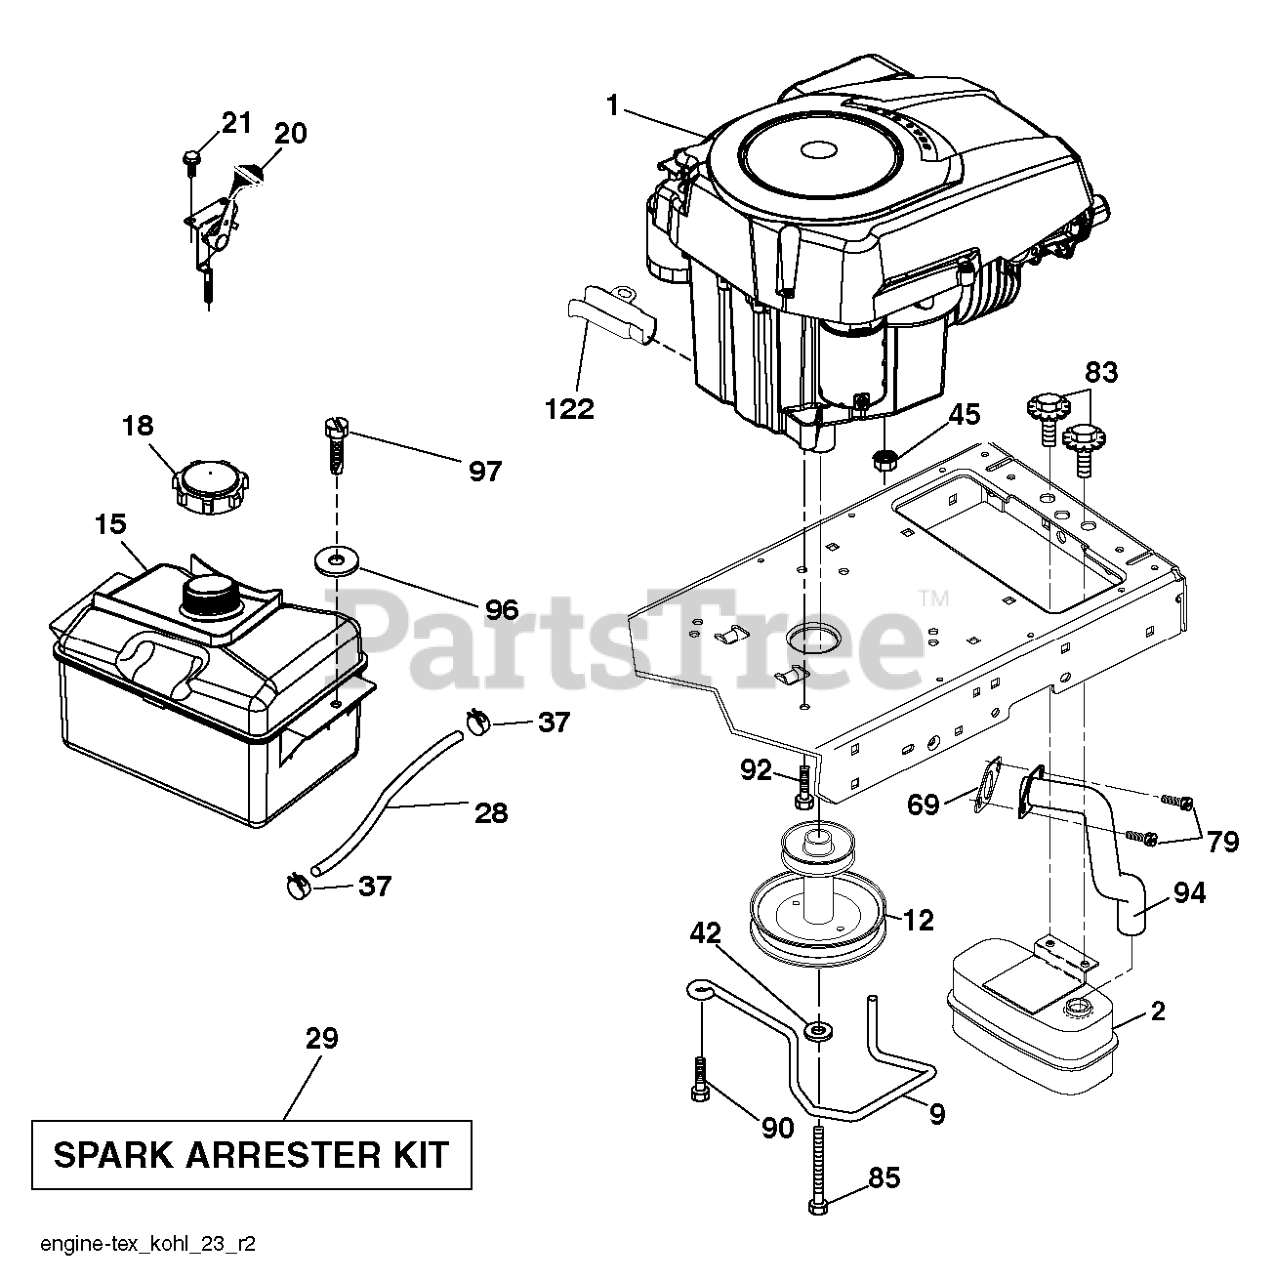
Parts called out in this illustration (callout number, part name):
2	MUFFLER.SINGLE.CYL.KOHL/B&S
9	KEEPER.BELT.ENGINE.4.2
12	PULLY ENGINE
15	RP TANK FUEL FRT 1.5 GAL
18	CAP ASM.FUEL.2.25"FR.
20	CONTROL.TH/CK.C.
21	SCREW.#10 X 0.750.BOS
28	LINE.FUEL.20
29	KIT.SPARK ARRESTOR 794945 B&S
37	HOSE CLAMP
42	LOCKWASHER
45	NUT
69	REPL BY 532 27 22-93
79	SCREW.SOCKET HD.5/16-1
83	BOLT.5/16-18UNCX3/4 W/SEMS.BLK
85	BOLT HEX 7/16-20X4-1/4"
90	SCREW 3/8-16X1
92	SCREW 3/8-16X1
94	EXHAUST.TUBE.B&S.
97	SCREW HEXWSHR 1/4-20X3/4
122	EXTENSION DRAIN OIL
